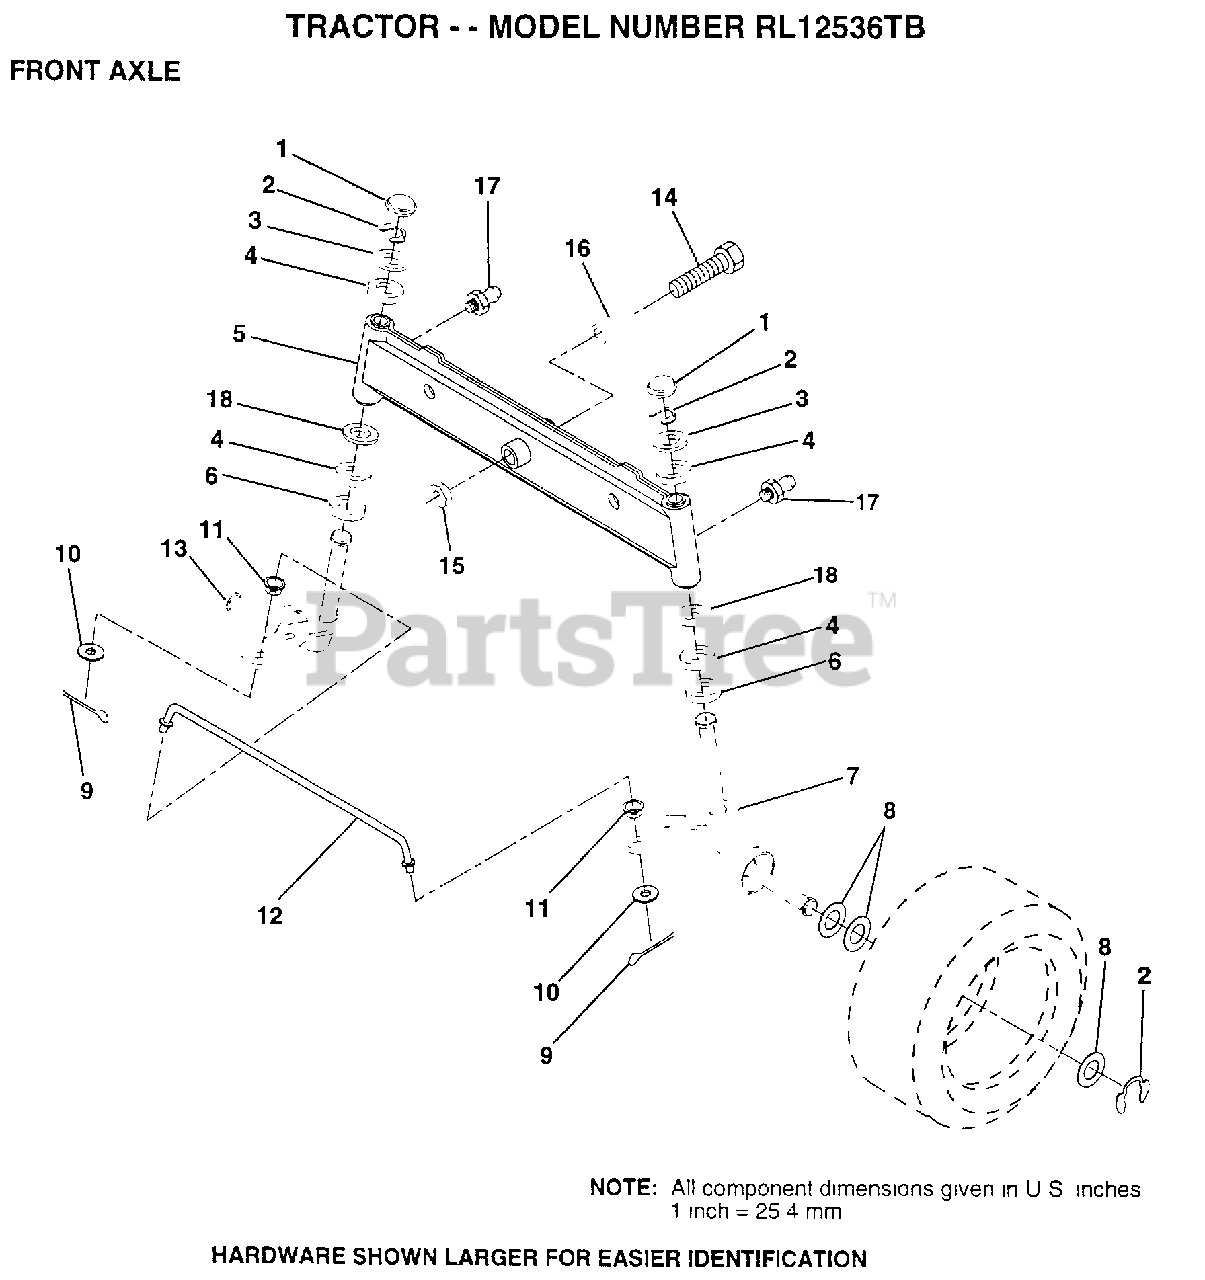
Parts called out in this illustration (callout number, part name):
1	CAP
2	RING
3	WASHER
4	COL. SRTG. BEAR.
5	AXLE ASM FRONT
6	WASHER .T
7	SPINDLE ASM RH
8	WASHER
9	COTTER PIN
10	WASHER
11	BUSHING.DRAGLINK
12	TIE ROD
13	SPINDLE ASM LH
14	BOLT HEX 5/8-11
15	"NUT-LOC,FLANGE LT"
16	BEARING
17	ZERK M
18	WASHER
